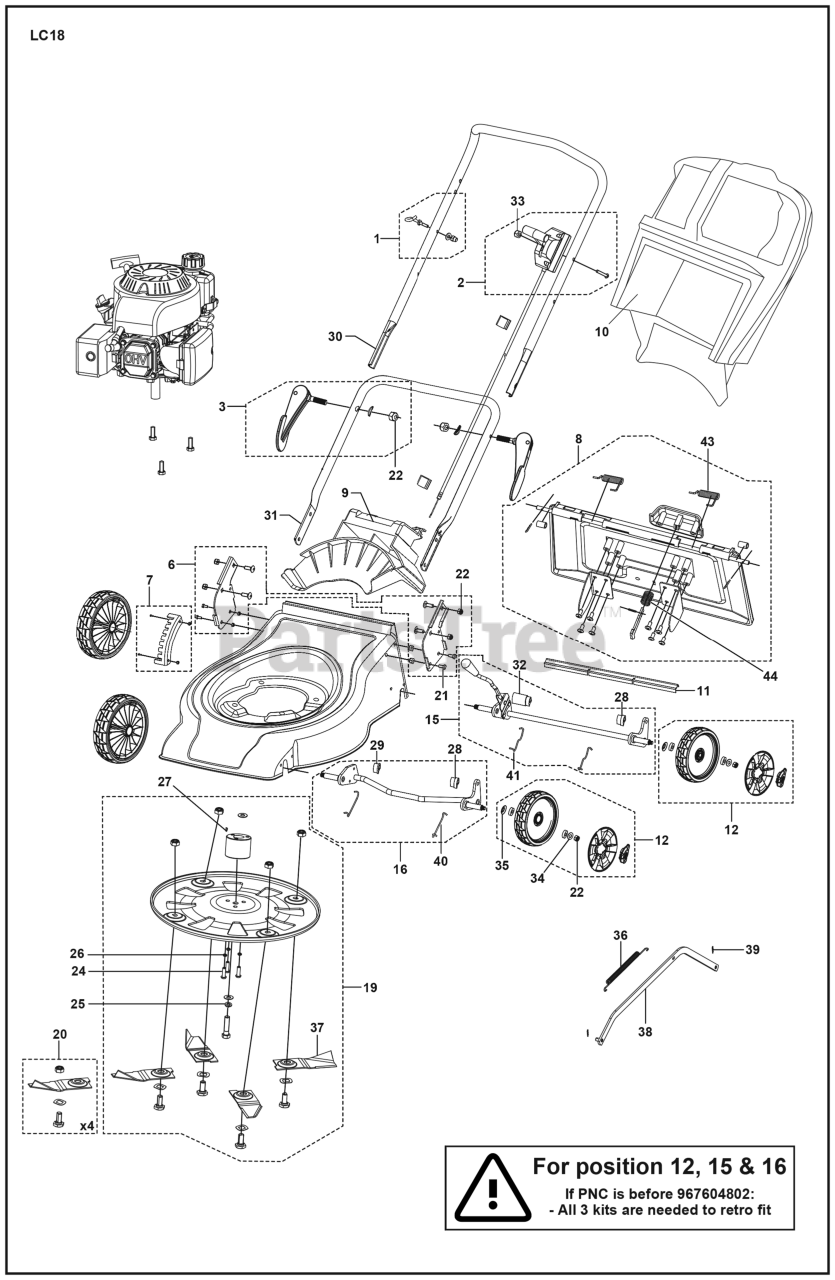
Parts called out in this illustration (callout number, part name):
21	BOLT - M8X16
22	LOCKNUT M8
25	Spring Washer
26	WASHER SPRING LOCK WASHER WITH
33	LOCKNUT M6
